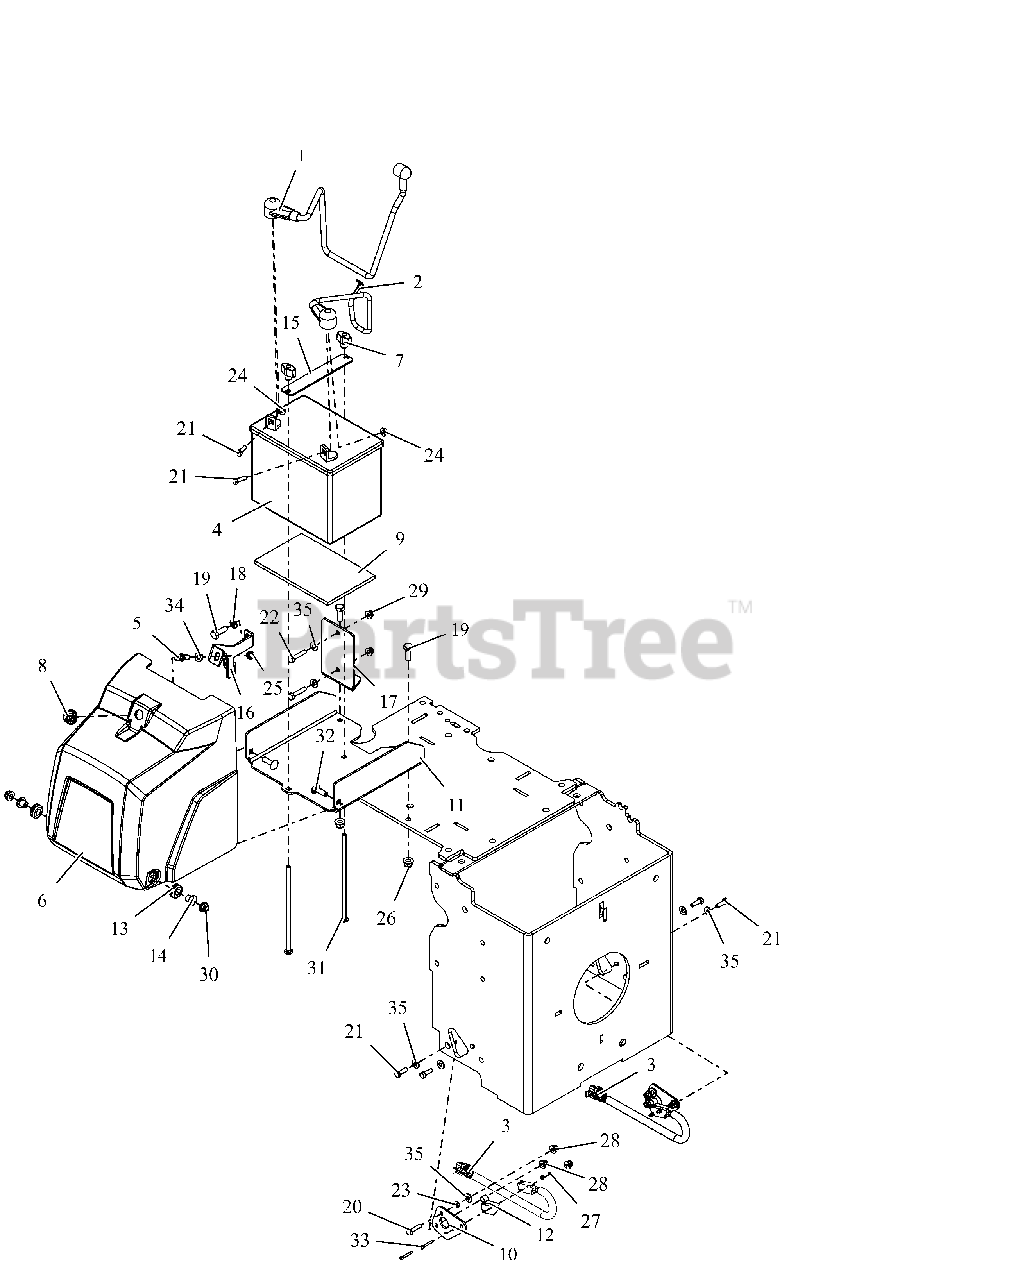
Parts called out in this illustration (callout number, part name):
1	CABLE, POSITVE BATTERY 16.75"
2	CABLE, BATTERY NEGATIVE 22.5"
3	ASM, SWITCH W/LEADS&CONNECTOR
4	BATTERY, 300 CCA 10U1L
5	STUD- BALL
6	COVER, BATTERY
7	KNOB, WING - .25-20 UNC
8	GROMMET, 10MM BOLLHOFF
9	PAD,BATTERY
10	PLATE, BASE
11	SUPPORT, BATTERY
12	SPRG, SWITCH
13	GROMMET, COVER MNT
14	BSHG, FRONT COVER
15	STRAP, BATTERY
16	BRKT, BATTERY DOOR CATCH
17	BRKT, MOUNT-REGULATOR-KOHLER
18	WSHR,LK-REG .312X.078 ZCC
19	BLT, HEX M8-1.25X25 G8.8 ZCC
20	BLT, HEX M6-1.0 X 25 G8.8 ZCC
21	BLT, HEX M6-1.0 X 20 G8.8 ZCC
22	BLT, HEX .25-20X1.25 G5 ZCC
23	NUT, HEX-JAM M6-1.0 G8.8 ZCC
24	NUT, SPNLK-FLG M6-1.0 G8.8 ZCC
25	NUT,NYL M8-1.25 G8.8 ZCC
26	NUT,NYL-FLG M8-1.25 G8.8 ZCC
27	NUT,NYL M3-.5 G8.8 ZCC
28	NUT,NYL-FLG M6-1.0 G8.8 ZCC
29	NUT,NYL-FLG .25-20 GF ZCC
30	NUT,NYL-FLG .31-18 GF ZCC
31	BLT,RHSN .25-20X7.00 G2 ZCC
32	BLT,RHSSN .31-18X1.00 G5 ZCC
33	SCR,SKH,M3-.5 X 25 12.9ZC120
34	WSHR,FLT .323X.625X.062 ZCC
35	WSHR,FLT .281X.625X.065 ZCC
